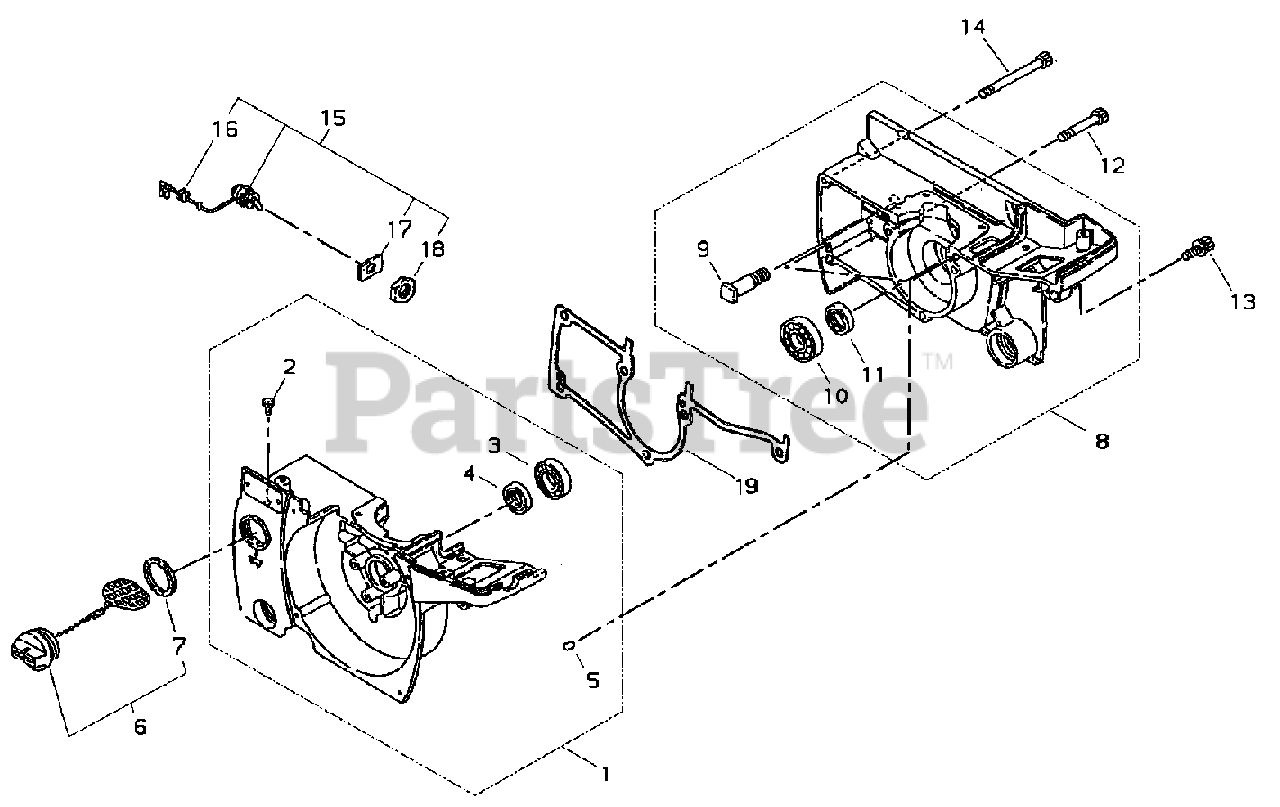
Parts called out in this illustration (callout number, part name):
1	CRANKCASE ASSY - LEFT
2	VALVE, CHECK
3	BEARING, BALL 6001 C3
4	SEAL, OIL - 12
5	PIN - LOCATING
6	CAP ASSY
7	GASKET, CAP
8	CRANKCASE ASSY - RIGHT
9	STUD, GUIDE BAR
10	BEARING, BALL - 6201C3
11	SEAL, OIL - 12
12	SCREW - 5X30
13	BOLT - 5X18
14	BOLT - 5X45
15	IGNITION SWITCH KIT
16	GROMMET
17	PLATE, SWITCH
18	NUT - 10
19	GASKET, CRANKCASE
